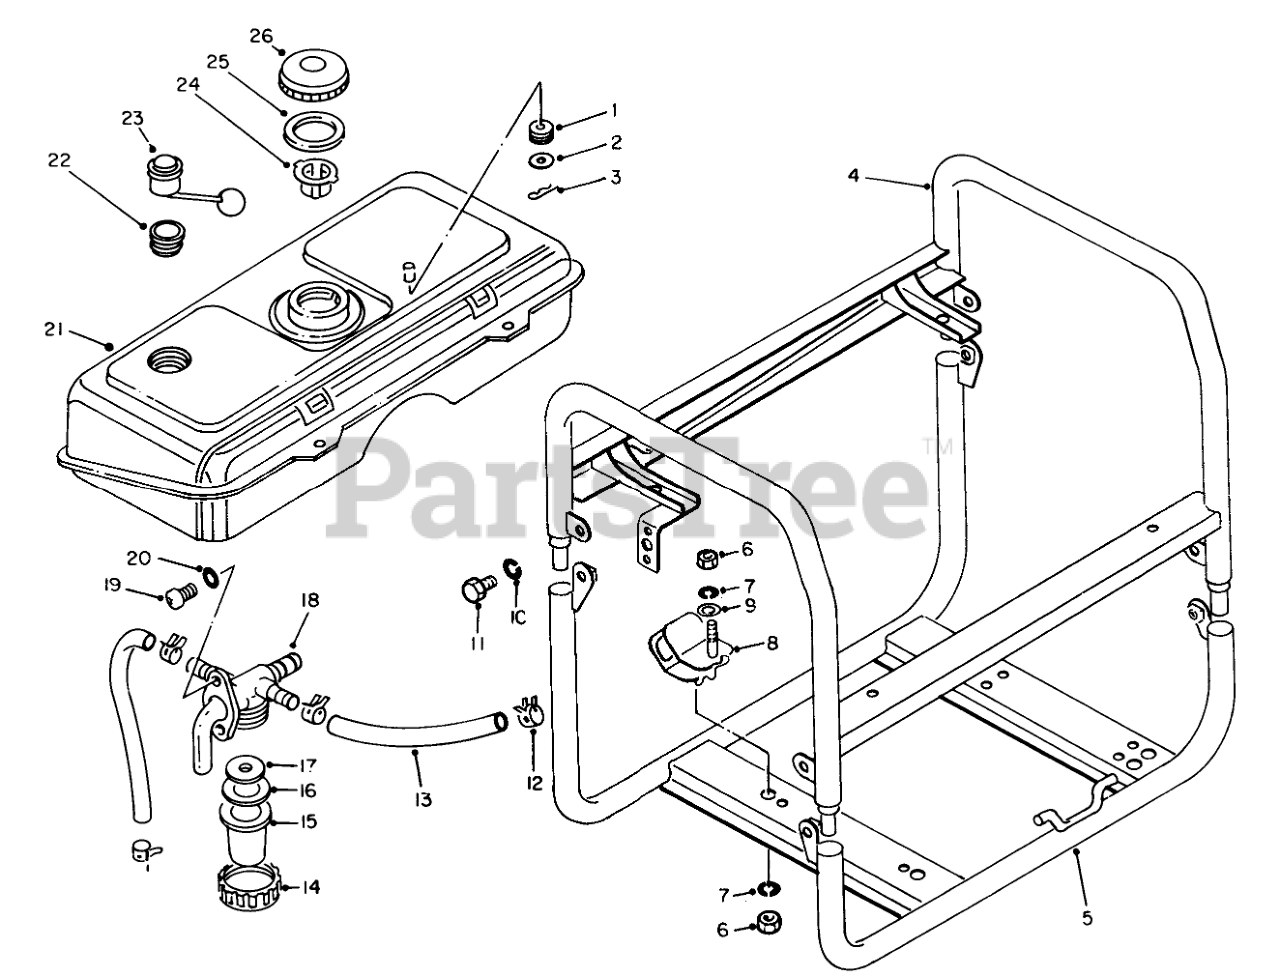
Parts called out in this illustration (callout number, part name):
1	CUSHION
2	WASHER
4	Frame-Upper
5	E-Ring
7	WASHER-LOCK
8	Mounting Engine
9	Washer
10	Lockwasher
16	GASKET
17	FILTER
18	Fuel Cock Assembly (Incl. Ref. #14-17)
19	Screw
20	Lockwasher
21	Fuel Tank
22	Gasket
23	Gauge Assembly Fuel (Incl. Ref. #22)
24	FILTER
25	GASKET
26	Cap (Incl. Ref. #25)
